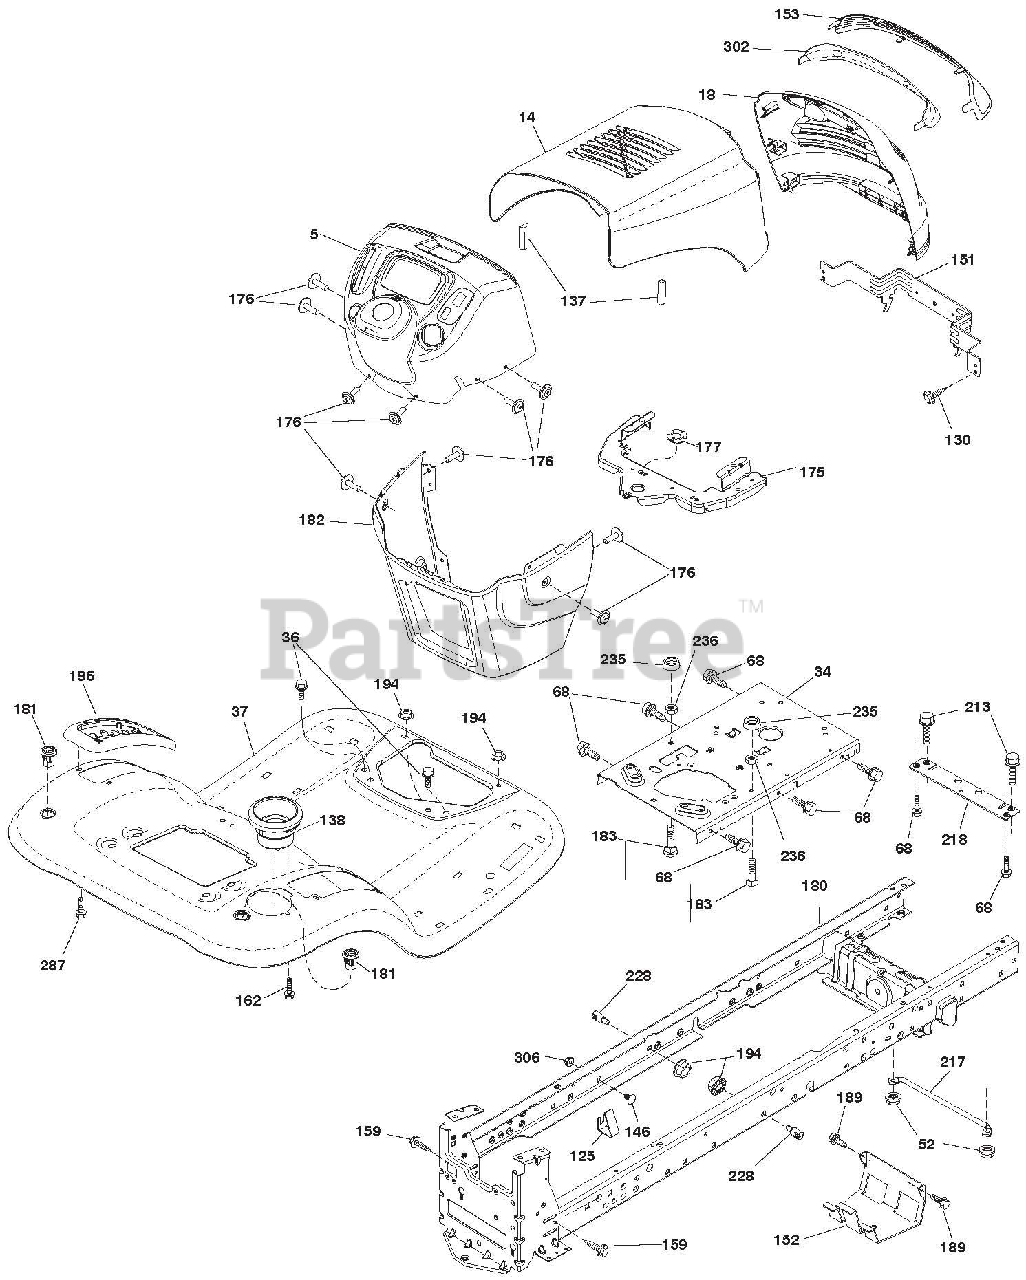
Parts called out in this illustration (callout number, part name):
34	PLATE ENGINE WELDED CHASSIS
36	SCREW.5/16-18X3/4.SMGML.TAP/R
37	FENDER TLT W/CPH W/FW 422
52	Nut, Hex, Crownlock 5/16-18
68	SCREW.THDROL.5/16-18 X 1/2TYTT
125	CLIP.FUEL.LINE
137	BUMPER.HOOD.LARGE. 1.75"
138	CUPHOLDER TL TEX 428
151	Bracket Pivot
152	SHIELD.BROWNING.W/TEX
153	LENS.GRILLE.BAR
159	SCREW.HEXWSH THDR3/8-16X3/4.BL
162	SCREW.HEX.WSH.HI-LO.1/4X1/2UNC
175	CROSSMEMBER.LT
176	SCREW.#10-24X5/8.RND.QUDRX.GIM
177	BUSHING.STEERING.LT
180	Chassis
181	BUSHING MNT FEND CRGO BLK TEX
182	DASH LOWER.LT.CCS
183	BOLT.FIN.HEX.5/16-18 UNC X1-1/
189	SCREW.5/16-18X3/4.SMGML.TAP/BL
194	Nut, Lock Hex Flange 5/16-18 u
196	CONSOLE ASM.DECKLFT.BL/RBT.TLT
213	BOLT.HEX.HD.1/4-20UNC X 3/4
217	ROD.PIVOT.HOOD
218	X-PIECE.HOOD.STOP.NON/STEALTH
228	STUD.FASTNER.W/'D'ANTI-ROTATIO
235	SPACER.FENDER
236	NUT.CENTER LOCK.5/16-18 UNC
287	SCREW.HEX.WASHEAD.1/4-20 X 3/8
302	Insert Lens Reflect
306	Nut, Hex, Flangelock 3/8-16
